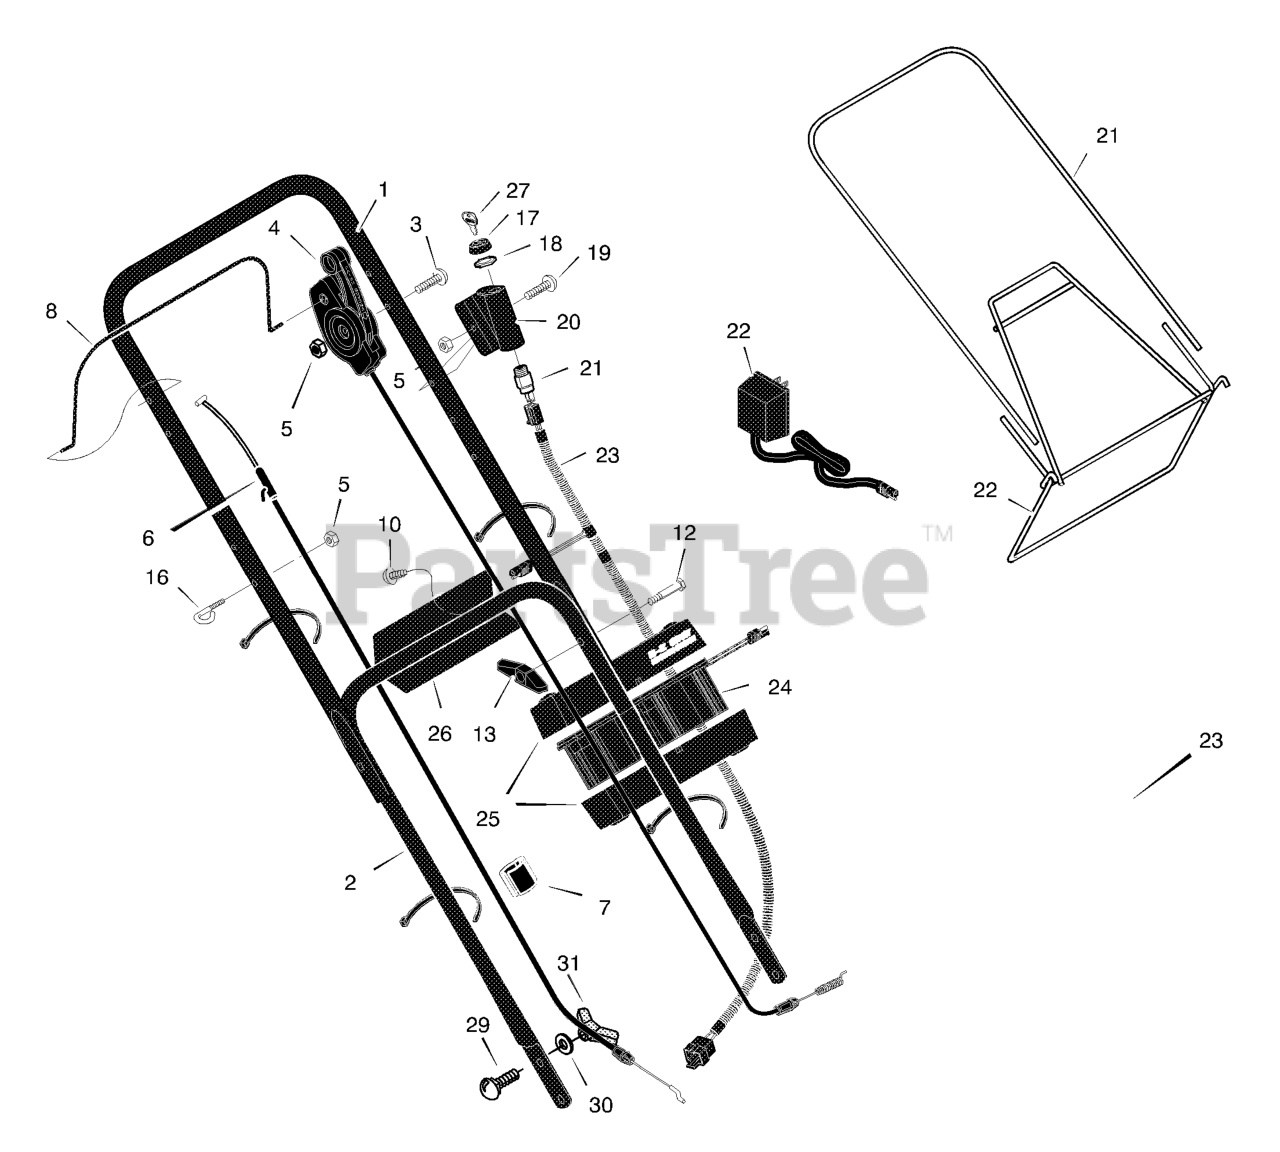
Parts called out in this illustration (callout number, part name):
1	Handle, Upper (Gray)
2	Handle, Lower (Gray)
4	Control, Drive
5	Locknut
6	Cable, Stop
7	Fastener, Single Cable
8	Lever, Stop
13	Knob
16	Guide, Rope
17	Cap
18	Nut
20	Cover, Ignition
21	Switch Ignition & Key
21	Frame, Top
22	Charger, Battery
22	Frame Assembly
23	Harness, Wiring
23	Bag, Cloth
24	Battery
25	Case, Battery
26	Bracket, Battery
27	Key, Ignition
29	Bolt, Carriage
31	Knob, Plastic
